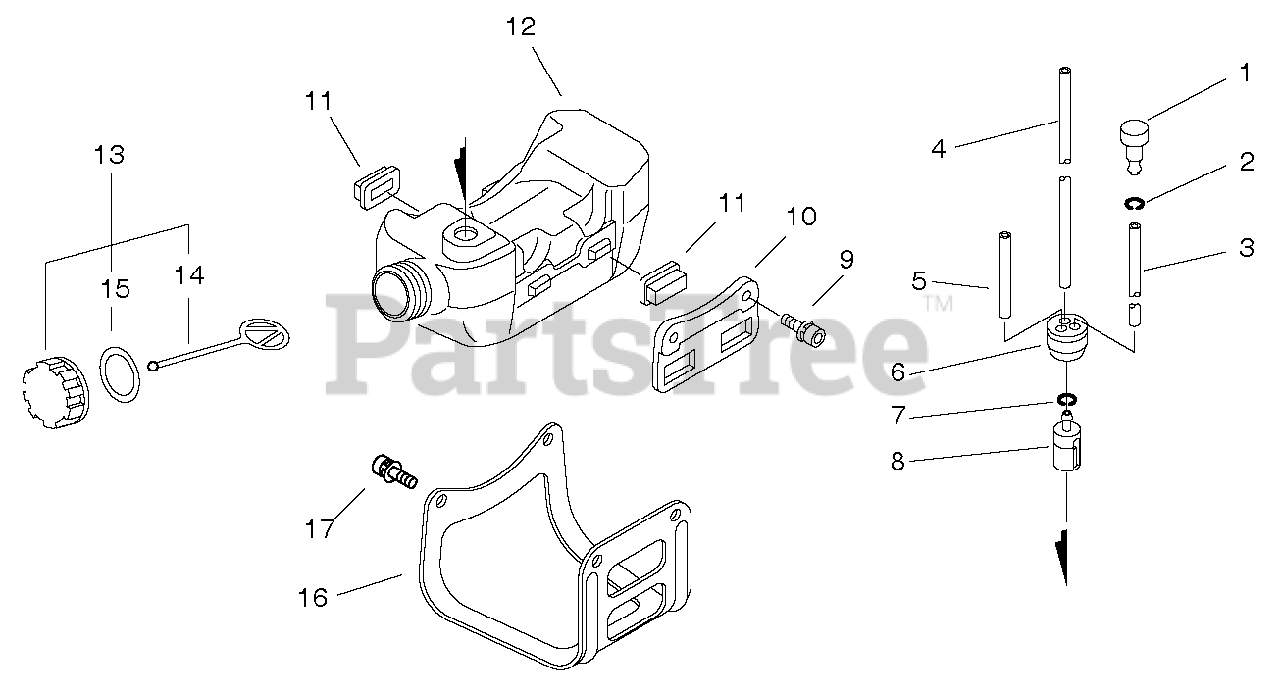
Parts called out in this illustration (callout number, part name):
1	VENT, FUEL TANK
2	CLIP - 5.5
3	PIPE - 3X5X90 -- BLACK
4	PIPE - 3X5X180 -- BLACK
5	PIPE - 3X6X90 -- CLEAR
7	CLIP - 6
8	FILTER, FUEL
9	SCREW - 5X20
10	BRACKET, FUEL TANK
11	CUSHION, FUEL TANK
12	TANK, FUEL
13	CAP ASSY - ORANGE
14	CONNECTOR, CAP
15	GASKET, CAP
16	GUARD, FUEL TANK
17	SCREW - 5X12
